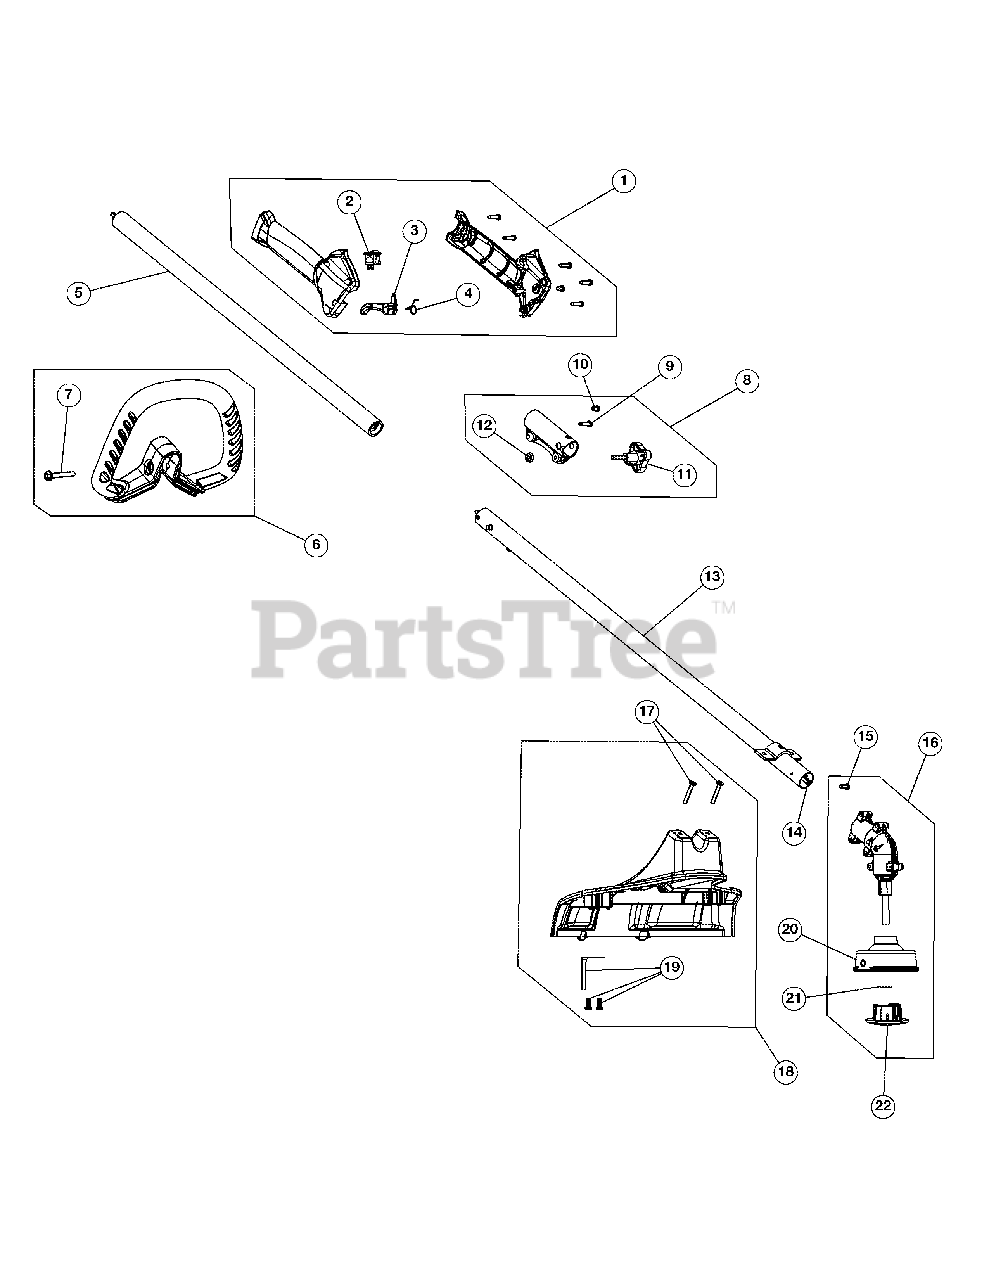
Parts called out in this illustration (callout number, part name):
1	Throttle Housing Assembly (Incl. 2-4)
3	Throttle Trigger
4	Throttle Trigger Spring
5	Upper Shaft Housing Assembly
6	D-Handle (Incl. 7)
7	D-Handle Hardware
8	Split Boom Coupler (Incl. 9-12)
9	Anti-Rotation Screw
11	Adjustment Knob
12	Knob Retainer Nut
13	Lower Shaft Housing Assembly
14	Lower Flexible Drive Shaft
15	Anti-Rotation Screw
16	Gear Box Assembly (Incl. 15, 20 & 21)
17	Shield Mounting Screws
18	Shield Assembly (Incl. 17 & 19)
19	Blade Assembly
20	Fixed String Head Assembly (Incl. 21 & 22)
21	Retainer
22	Fixed String Cap
